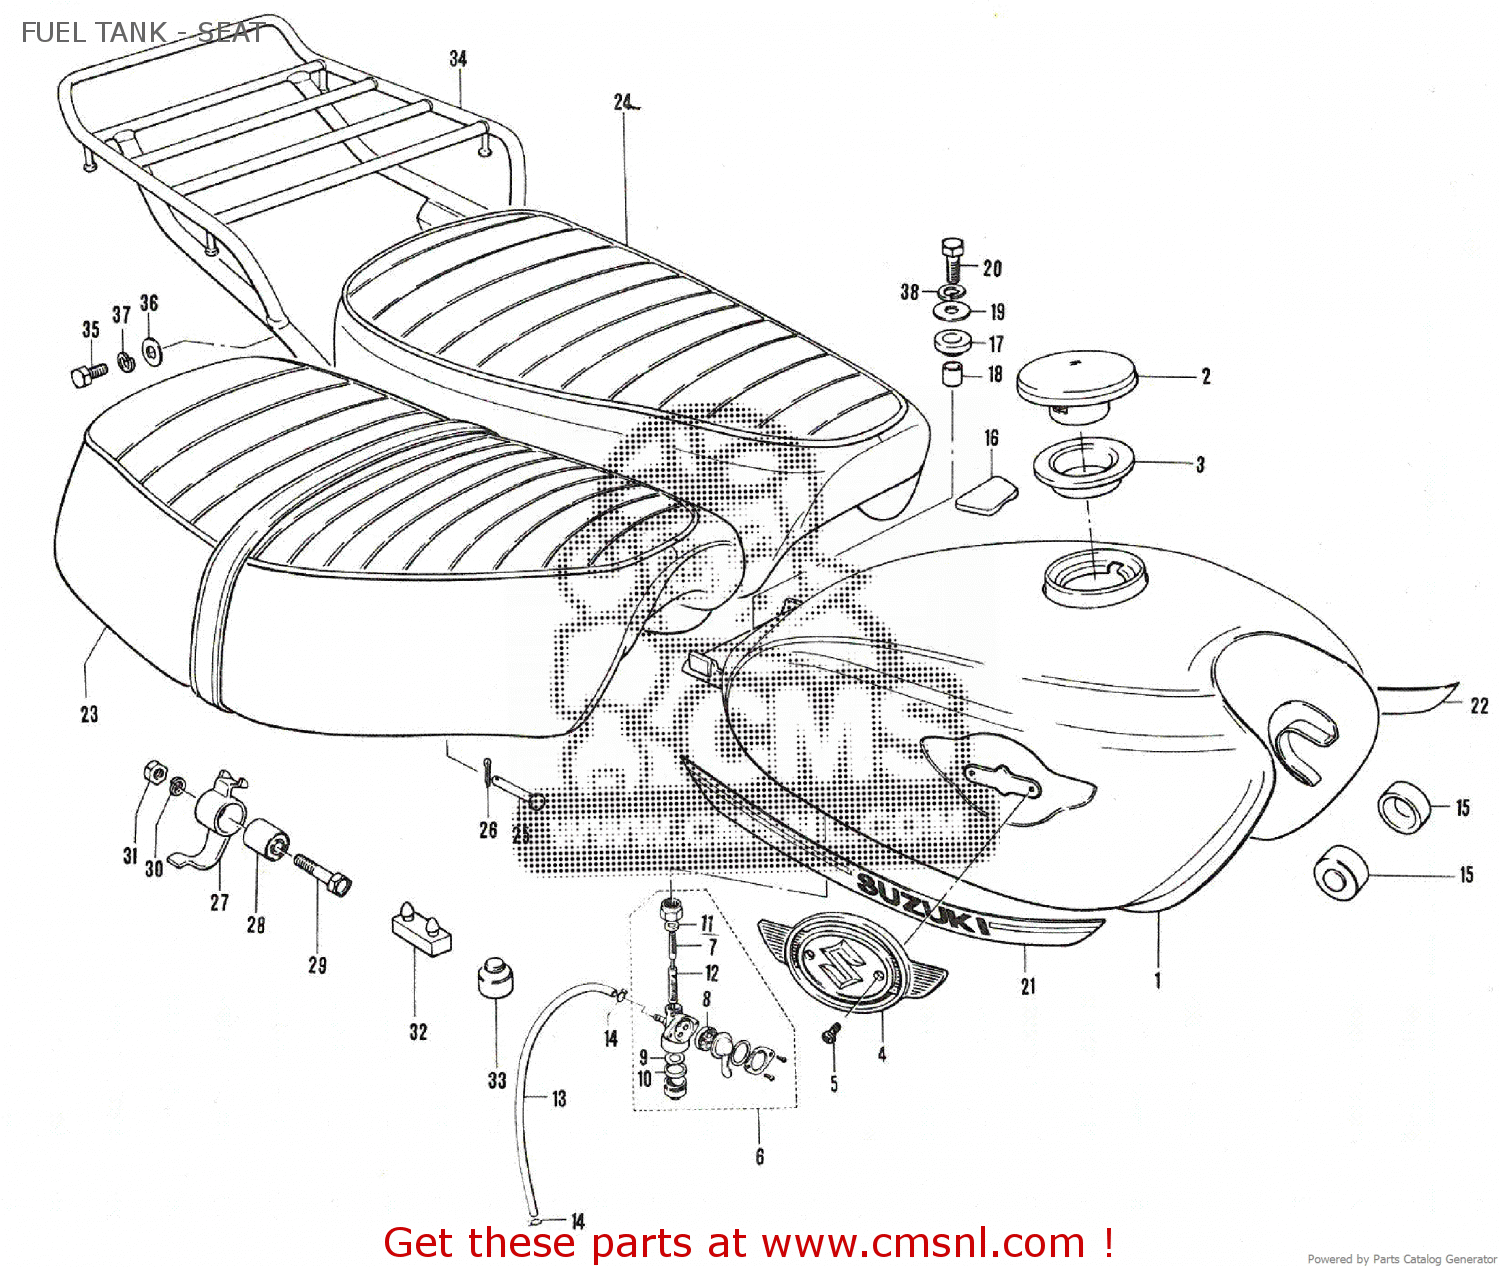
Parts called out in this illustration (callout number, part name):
1	TANK ASSEMBLY,FUEL
2	CAP SET,FUEL TANK
3	GASKET,FUEL TANK CAP (NAS)
4	EMBLEM
5	SCREW
6	COCK ASSEMBLY,FUEL
7	FILTER,FUEL
8	GASKET,LEVER (NAS)
9	NET,STRAINER
10	GASKET,STRAINER CUP (NAS)
11	GASKET,FUEL COCK (NAS)
12	NET,HOSE
13	HOSE
14	CLIP
15	CUSHION
16	CUSHION
17	CUSHION
18	SPACER (8.8X12X15.5)
19	WASHER (8.5X29X1.6)
20	BOLT
21	FUEL TANK RH STRIPING TAPE
22	FUEL TANK LH STRIPING TAPE
24	SEAT ASSEMBLY
25	PIN
26	PIN
27	STRIKER,SEAT LOCK
28	BUSHING
29	SMALL HEXAGON BOLT
30	LOCK WASHER
31	NUT
32	CUSHION
33	CUSHION
34	CARRIER
35	HEXAGON BOLT
36	WASHER
37	LOCK WASHER
38	LOCK WASHER
